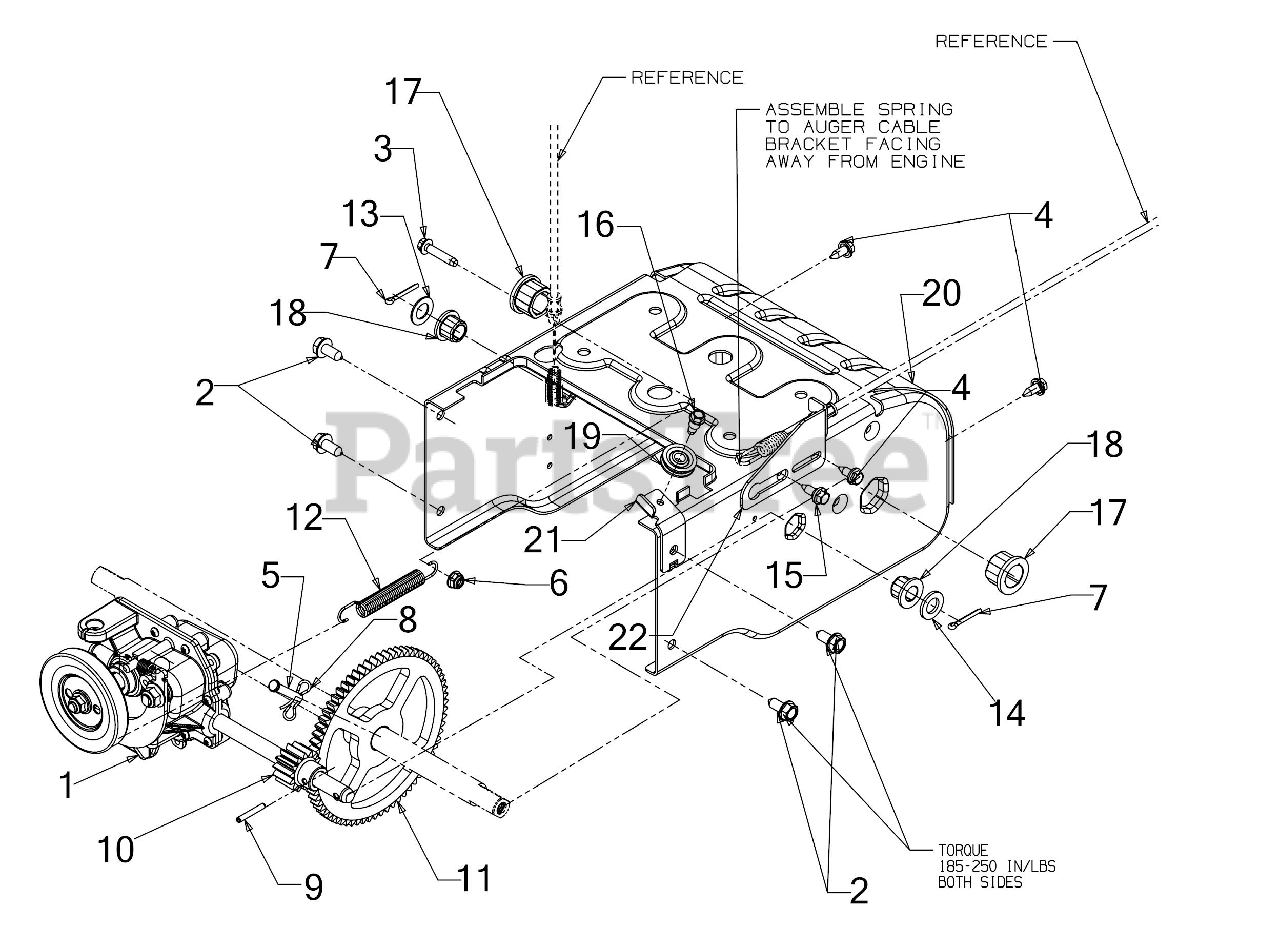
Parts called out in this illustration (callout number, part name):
1	SNOW TRANSMISSION ASSEMBLY
2	SCREW 5/16-18 x .750
3	SCREW 1/4-20 x 1.25
4	SCREW 1/4-20X.625
6	FLANGE LOCK NUT
7	COTTER PIN-1/8 D
8	BOW TIE COTTER PIN 1/4-5/16
9	SPRING PIN ROLL
10	PINION:14T
11	GEAR 70T
12	EXTENSION SPRING
13	FLAT WASHER
14	FLAT WASHER .535 x .930 x .090
15	SHOULDER SCREW
16	SHOULDER SCREW
17	FLANGE BEARING
18	HEX FLANGE BEARING .506ID x .590LG
19	CABLE GUIDE ROLLER
20	WHEEL FRAME HOUSING
21	CABLE GUIDE BRACKET
